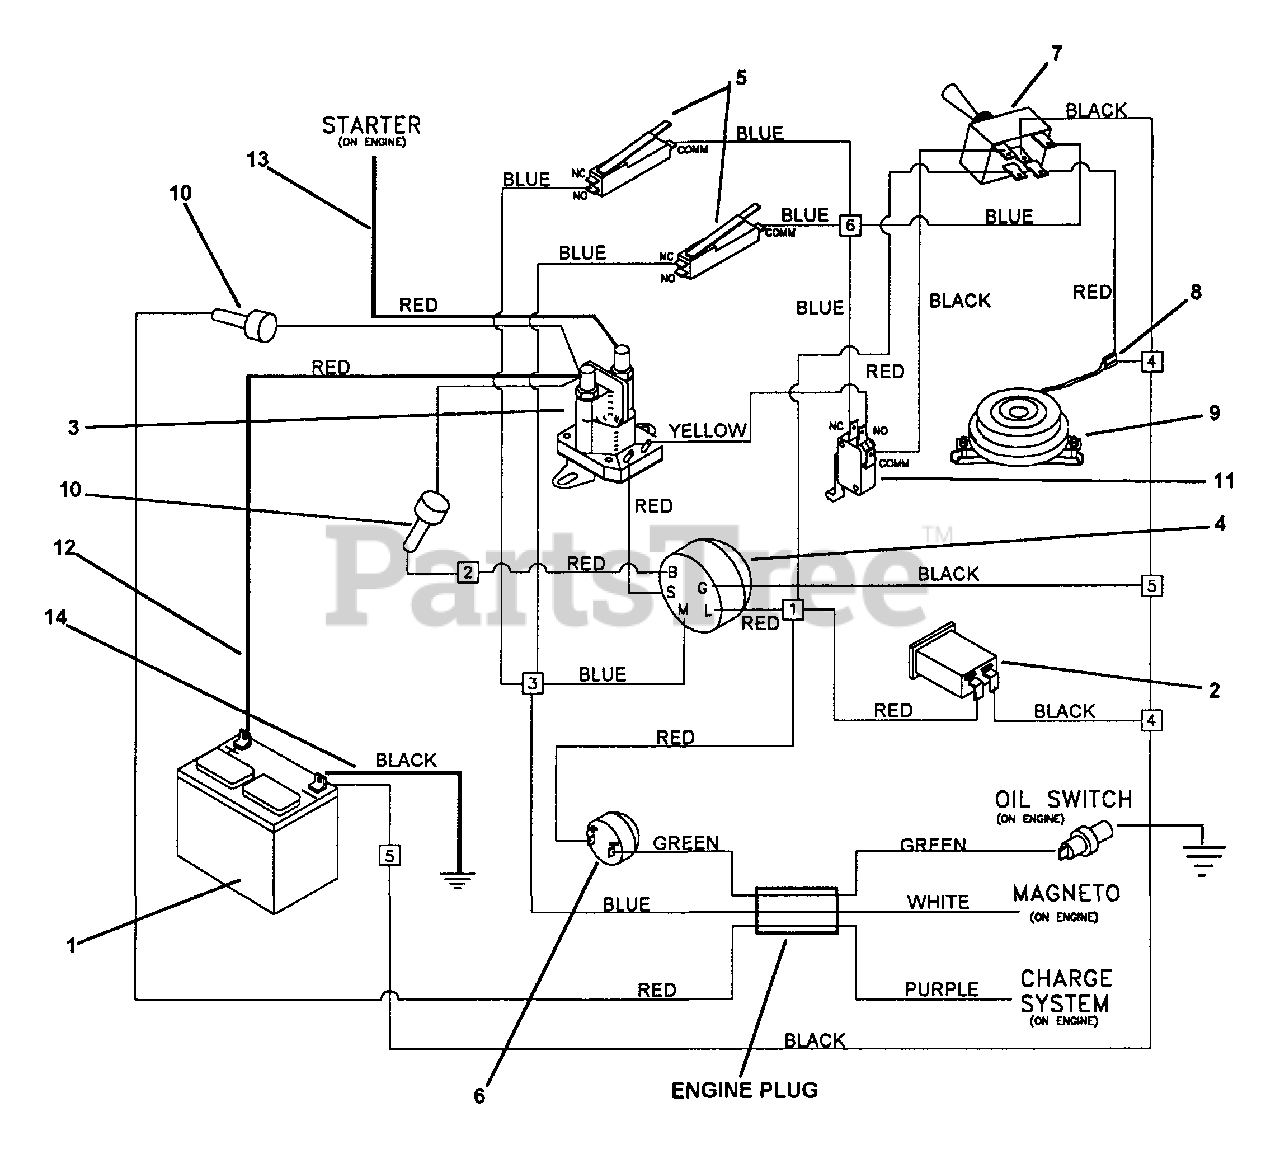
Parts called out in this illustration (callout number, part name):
1	BATTERY
2	HOUR METER, 14, 18, & 20 HP
3	SOLENOID
4	START SWITCH
5	SWITCH, ENCL, SPDT 15A HINGED LEVER
6	BUZZER, 14, 18, & 20 HP
7	CLUTCH SWITCH
8	INSULATOR COVER (female end only)
9	ELECTRIC CLUTCH
10	FUSEHOLDER (INLINE)
10	FUSEHOLDER (INLINE) SPADE STYLE
10	FUSE, 30 AMP GLASS SLO-BLO
10	FUSE, 30 AMP SPADE STYLE
11	SWITCH, SPDT MINIATURE
12	CABLE, BATTERY, 31.75" W/ BOOTS
13	CABLE, STARTER, 31.75" WO/BOOTS
14	WIRE ASS'Y, 24" BLK. 8 GA. ENG./GRD., 14, 18, & 20 HP
14	6 PT. TERMINAL STRIP
